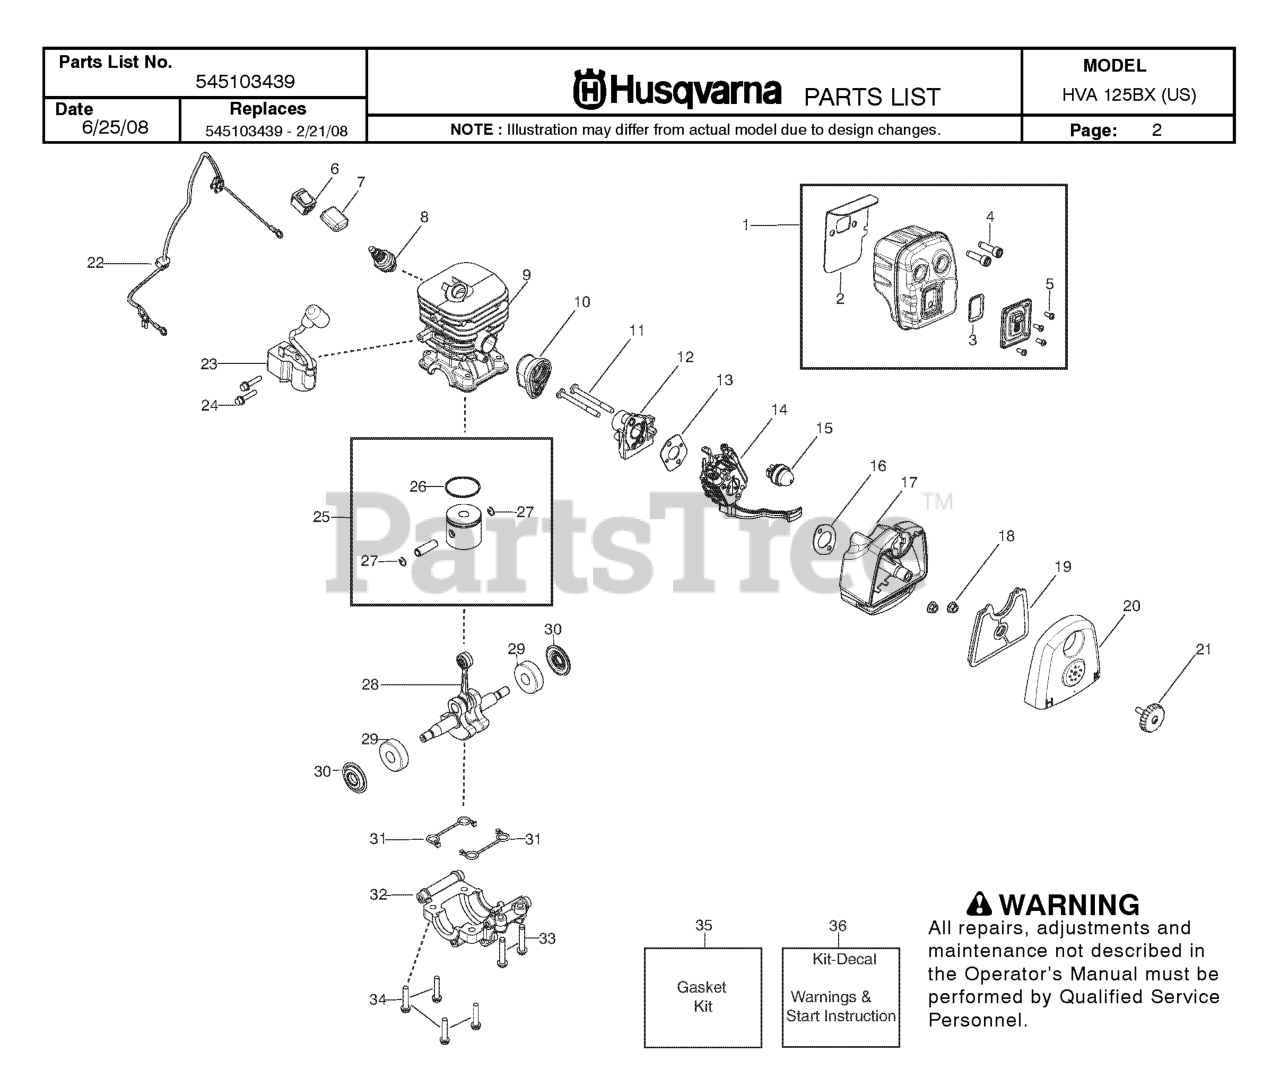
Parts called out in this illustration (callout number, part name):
1	ASSY, MUFFLER
3	KIT, SPARK SCREEN
4	BOLT MUFFLER
5	SCREW-6-19X5/16PLAST PA
6	KIT SWITCH
7	PROTECTOR, SWITCH
8	Accy - Spark Plug (RCJ6-Y)
9	CYLINDER -CHROME
10	BOOT, CARB
12	PLATE, CARB
14	KIT CARBURETOR
17	BASE, AIRBOX
19	Air Filters
20	COVER, AIRBOX
21	KNOB ASSY AIRBOX COVER
22	ASSY, LEADWIRE
23	IGNITION MODULE
24	SCREW M4 X .70 TT 16MM
25	KIT - PISTON
26	RING PISTON
27	WRIST PIN RET.
28	KIT, CRANKSHAFT
29	BEARING RADIAL BALL (6201)
30	CRANKSHAFT SEAL
32	CAP - BEARING
34	SCREW-M5-0.8 X 25MM(TAP)
